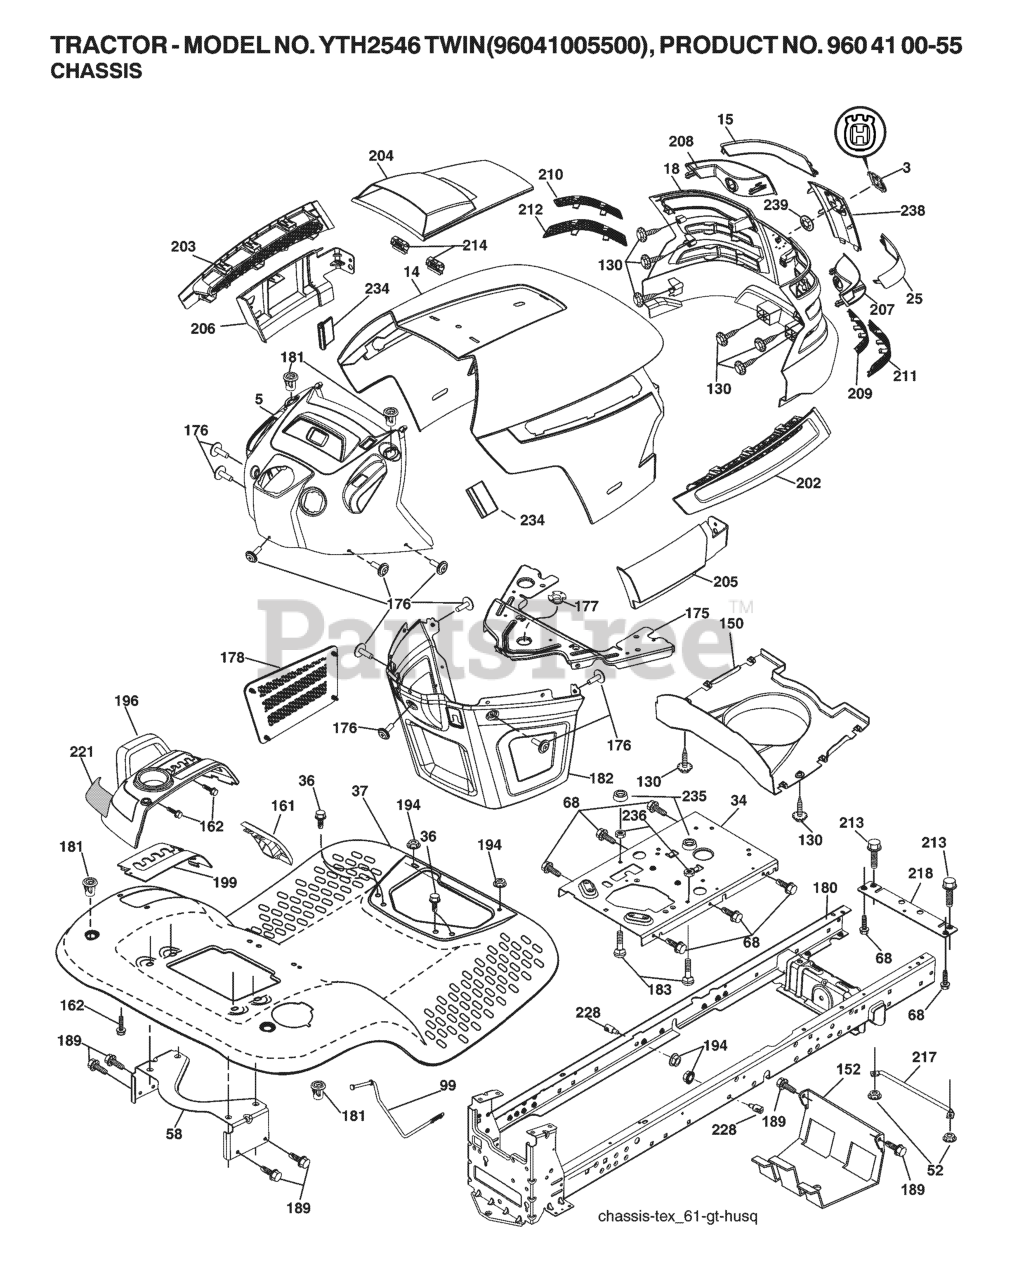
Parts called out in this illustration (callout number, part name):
3	RP LOGO
5	DASH.ASM.HUSQ.GT.E.RECT.W/CK
14	HOOD
15	LENS.LH.TEX.GT.HUSQ.CL
18	GRILL.ASM.HUSQ.TG/CRD.W/TRIM
25	LENS.RH.TEX.GT.HUSQ.CL
34	PLATE.ENGINE.WELDED.CHASSIS
36	SCREW 5/16"
37	FENDER.PNT.TX.GT.CH/FW.ORANGE
52	LOCKNUT
58	BRKT.SUPPORT.FNDR/TANK
68	Screw 5/16-18 x 1/2 Hex, Self Tapping 5/16-18 x 1/2
99	ROD ASM BYPASS
130	SCREW
137	BUMPER DASH
150	AIR.DUCT.HOOD.TEX.GT.HUSQ
152	SHIELD.BROWNING.W/TEX
161	CONSOLE.FUEL.WINDOW.HU
162	SCREW.HI-LO.CONSOLE
165	SUPPORT.TANK.REAR.W/TEX
175	PLATE.CROSSMEMBER.HUSQ
176	SCREW.#10-24X5/8.RN.QU
177	BUSHING, STEERING
178	CARGO.ASM.NET.TXGT.W/C
180	CHASSIS.WLDMT.TX.GT.05
181	BUSHING.MNT.FEND.CRGO.
182	DASH.LOWER.COMMON.12V.
183	BOLT.5/16-18X1-1/4 FULL.THREAD
189	SCREW
194	NUT LOCK HEX FLANGE 5/16-18
196	RP CONSOLE.ASM.DECKLFT.W/
199	PLATE.DECK.LIFT.HUSQVARNA.GT
202	VENT.SIDE.HOOD.HUSQ.RH.GREY
203	VENT.SIDE.HOOD.HUSQ.LH.GRAY
204	VENT.TOP.HOOD.HUSQVARN
205	SKIRT.HOOD.SIDE.HUSQ.RH.GREY
206	SKIRT.HOOD.SIDE.HUSQ.LH.GREY
207	BEZEL.RH.TEX.GT.HUSQ
208	BEZEL.LH.TEX.GT.HUSQ
209	INSERT.HEX.GRILL.HUSQ.GREY
210	INSERT.HEX.GRILL.HUSQ.
211	INSERT.HEX.GRILL.HUSQ.
212	INSERT.HEX.GRILL.HUSQ.
213	BOLT
214	CLIP.RETAINER.TINNER.
217	ROD PIVOT CHASSIS/HOOD
218	X-PIECE.HOOD.STOP.NON/
221	REFLECTOR.LH.TEX GT HU
228	STUD.FASTNER.W/ANTI-ROTATE
234	BUMPER.HOOD.TEX.HUSQVARNA
235	SPACER FENDER
236	NUT.CENTERLOCK.5/16-
238	TRIM.HUSQ.TG/CRD.SERVICE
239	NUT PUSH M
